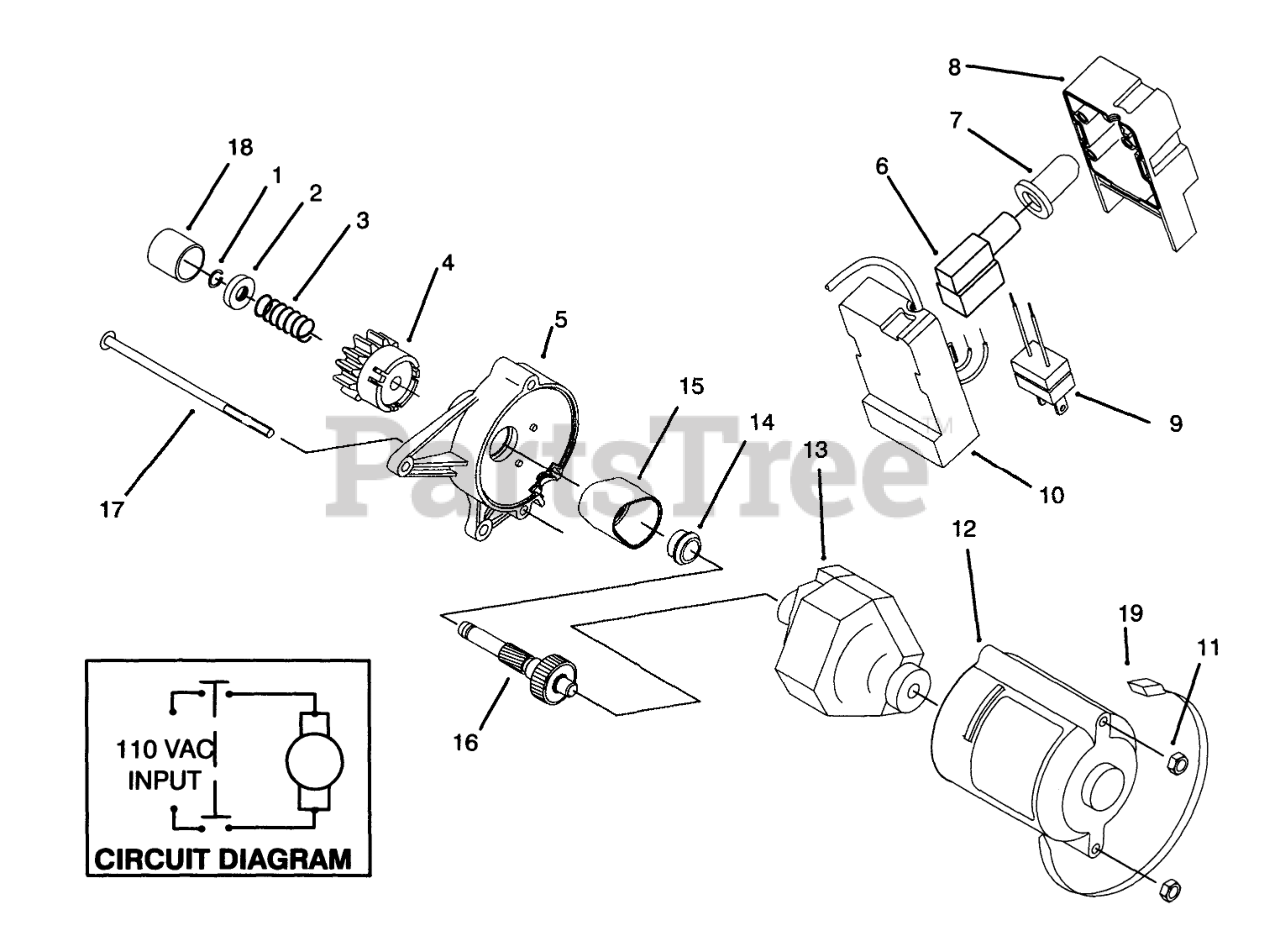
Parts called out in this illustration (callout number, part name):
1	RING-LOCK
2	PINION STOP
3	SPRING
4	PINION ASM
5	Housing-Starter
6	SWITCH-STARTER
7	BOOT-SWITCH
8	Cap-Switch Housing
9	Plug
10	OBS BASE X
11	NUT-LOCK, NI
12	HOUSING COVER
13	STARTER MOTOR ASM
14	BUSHING
15	COVER-GEAR
16	Asm-shaft & Gear
18	CAP-PINION
19	TIE-CABLE
